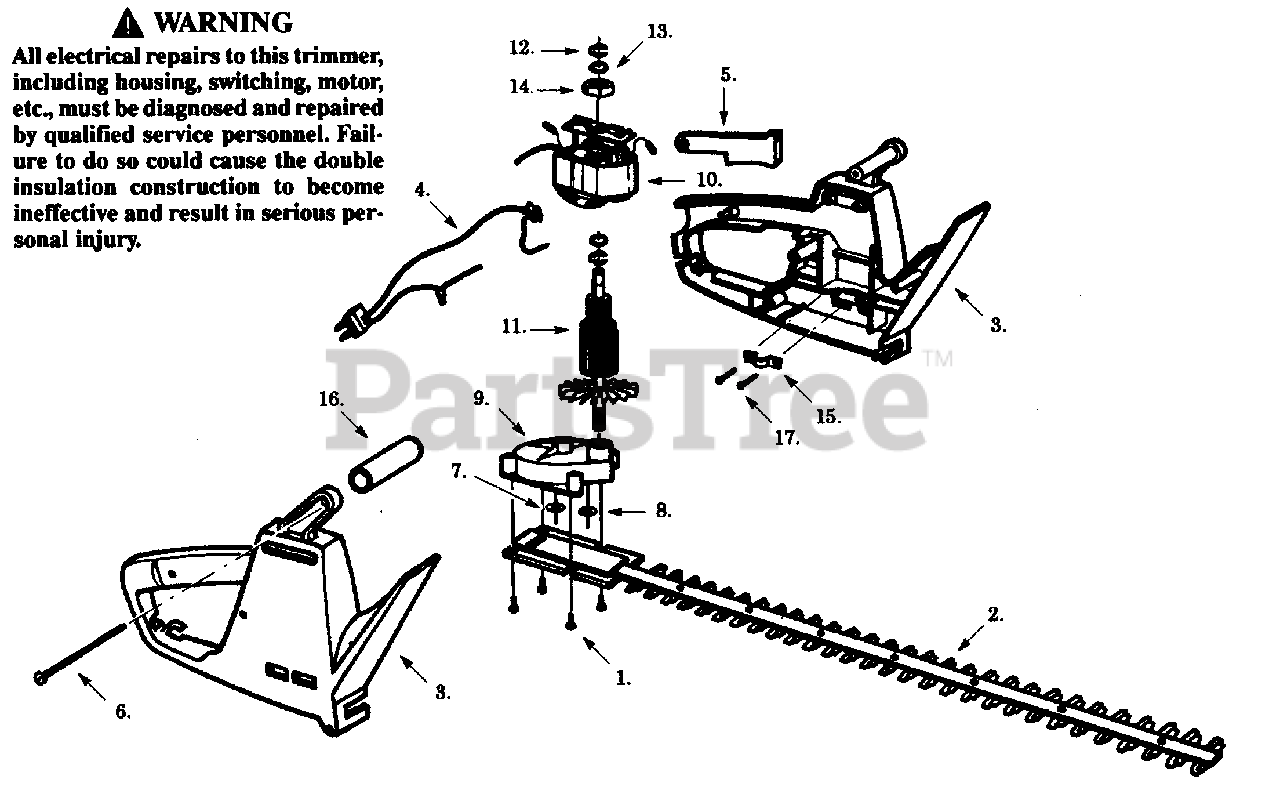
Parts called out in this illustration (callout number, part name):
2	Blade Ass'y. - HT1450
3	Housing Set
4	Switch/Plug Ass'y.
5	Trigger Switch
8	Drive Washer
9	Gear Box Ass'y. (Inc. Gear Assy)
10	Field Ass'y.
11	Armature Ass'y.
12	Retaining Ring
16	Cushon Handle
